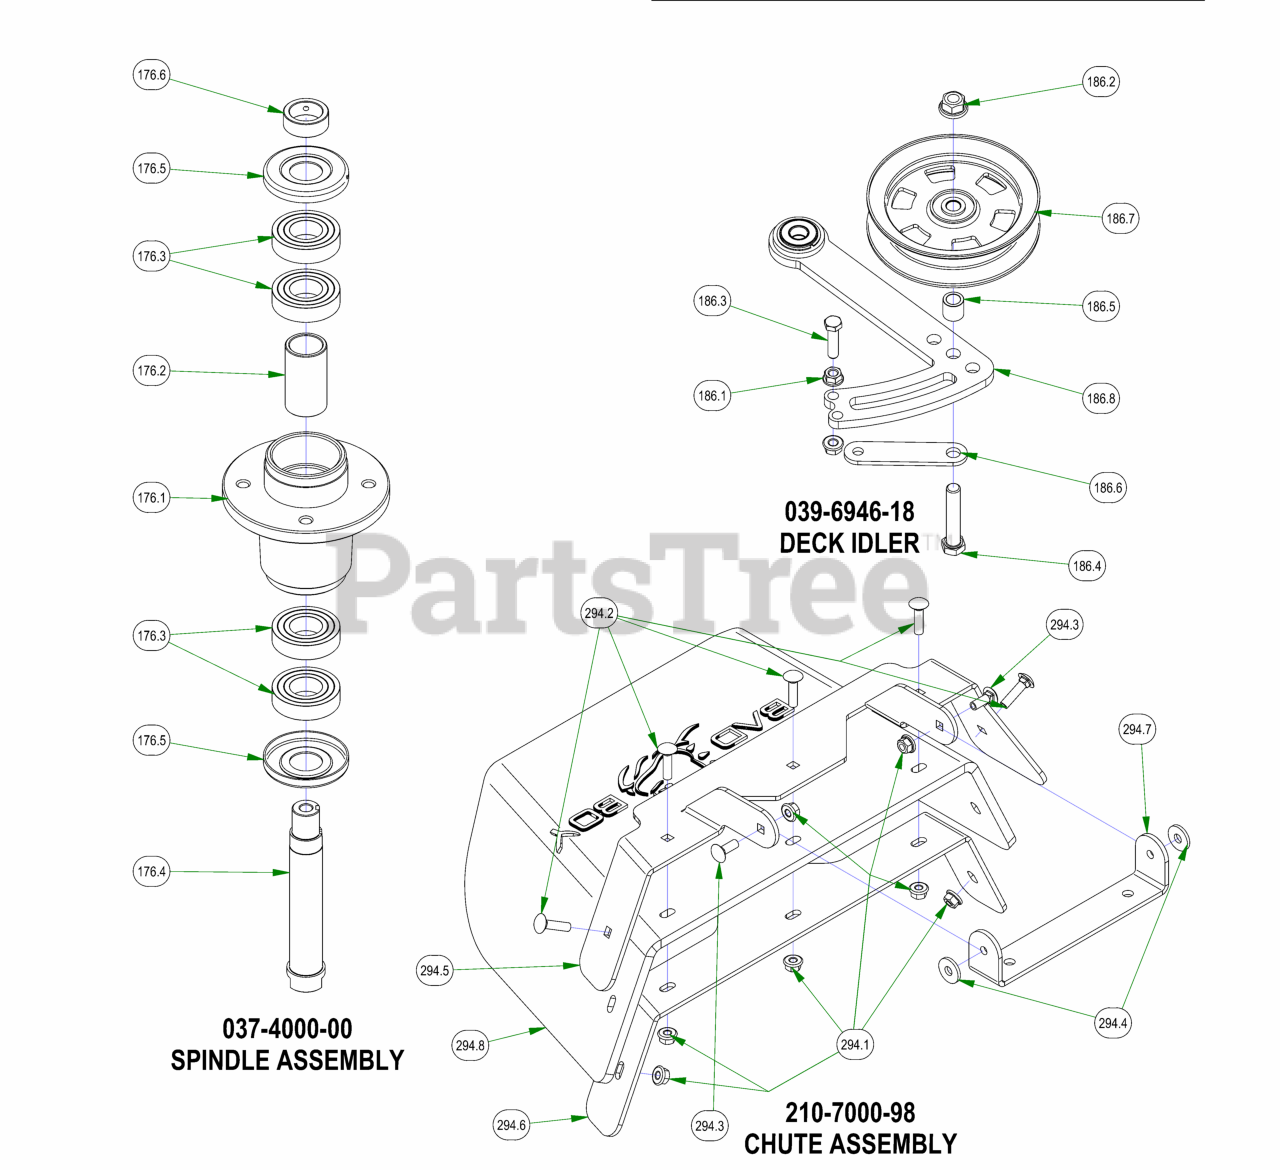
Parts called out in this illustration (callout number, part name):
176	OUTLAW SPINDLE ASSEMBLY
176.1	4000 Series Spindle Housing
176.2	4000 Series Spindle Spacer
176.3	Bearing - 6206
176.4	Spindle Shaft
176.5	Spindle Dust Cap
176.6	Locking Collar w/ 1/4"-20 Set Screw
186	2019 Rebel Rogue Deck Idler
186.1	3/8-16 HEX SERRATED FLANGE NUT HARD/ZINC
186.2	1/2-13 NYLON INSERT FLANGE LOCKNUT ZINC
186.3	3/8-16 X 1-1/2 HEX CAP SCREW (GR.5) ZINC
186.4	1/2-13 X 2-3/4 HEX CAP SCREW (GR.5) ZINC
186.5	.51 ID X .75 OD X .75 LGTH SOLID SPACER ZINC
186.6	Belt Tensioner Retainer Plate
186.7	5" Idler Pully
186.8	2019 Deck Tensioner
294	2019 Outlaw Gen2 Chute Assembly
294.1	5/16-18 NYLON INSERT FLANGE LOCKNUT ZINC
294.2	5/16-18 X 1-1/4 CARRIAGE BOLT ZINC
294.3	5/16-18 X 7/8 CARRIAGE BOLT ZINC
294.4	.360 ID X .983 OD X .120 THICK FLAT WASHER NYLON
294.5	2019 Upper Chute Bracket
294.6	2019 Lower Chute Bracket
294.7	2019 Chute Hanger
294.8	2019 Belted Chute with Logo
